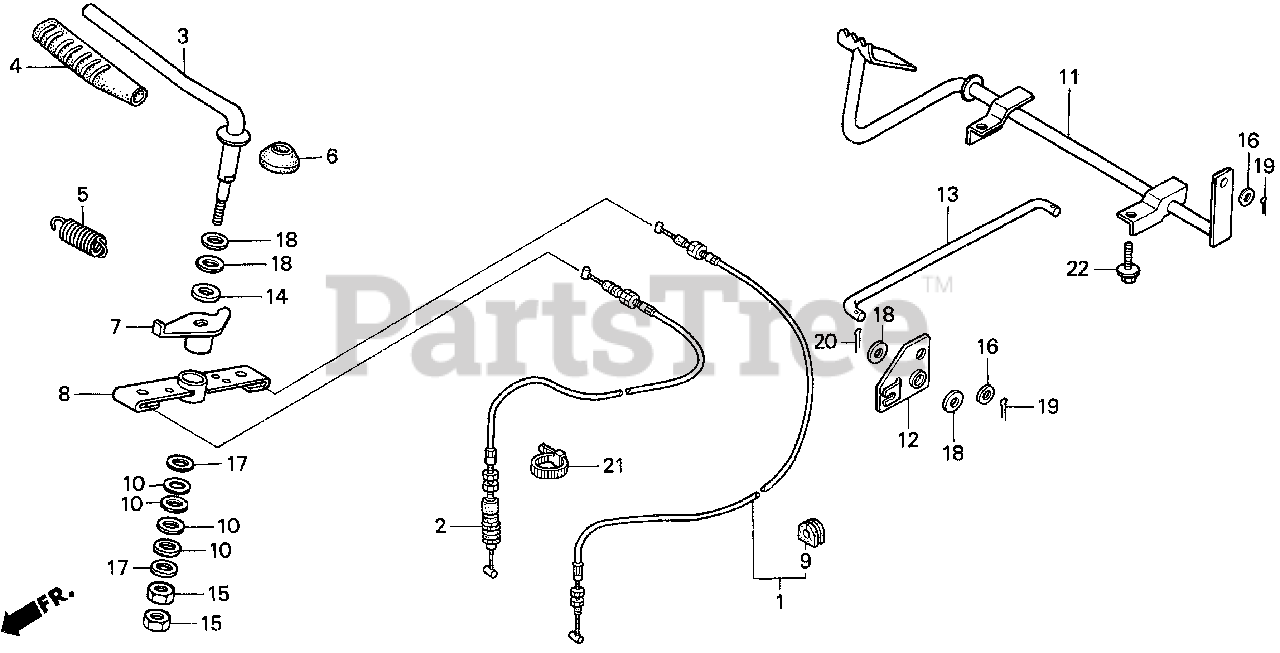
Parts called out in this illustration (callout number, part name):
1	CABLE, ACCELERATOR
2	CABLE, FOOT ACCELERATOR
3	LEVER, THROTTLE
4	GRIP, THROTTLE LEVER *YR161* (ORANGE)
5	SPRING, THROTTLE RETURN
6	COVER, THROTTLE LEVER
7	PLATE, THROTTLE CONTROL
8	HOLDER, THROTTLE CABLE
9	GROMMET, WIRE
10	WASHER, CONICAL SPRING
11	PEDAL, ACCELERATOR
12	ARM, ACCELERATOR PEDAL
13	ROD, ACCELERATOR PEDAL
14	WASHER, THRUST (12MM)
15	NUT, HEX. (8MM)
16	WASHER, PLAIN (6MM)
17	WASHER, PLAIN (8MM)
18	WASHER, FLAT (12MM)
19	PIN, COTTER (2.0X15)
20	PIN, COTTER (2.0X22)
20	PIN, COTTER (2.0X35)
21	BAND B1, CABLE
22	BOLT, FLANGE (6X10)
